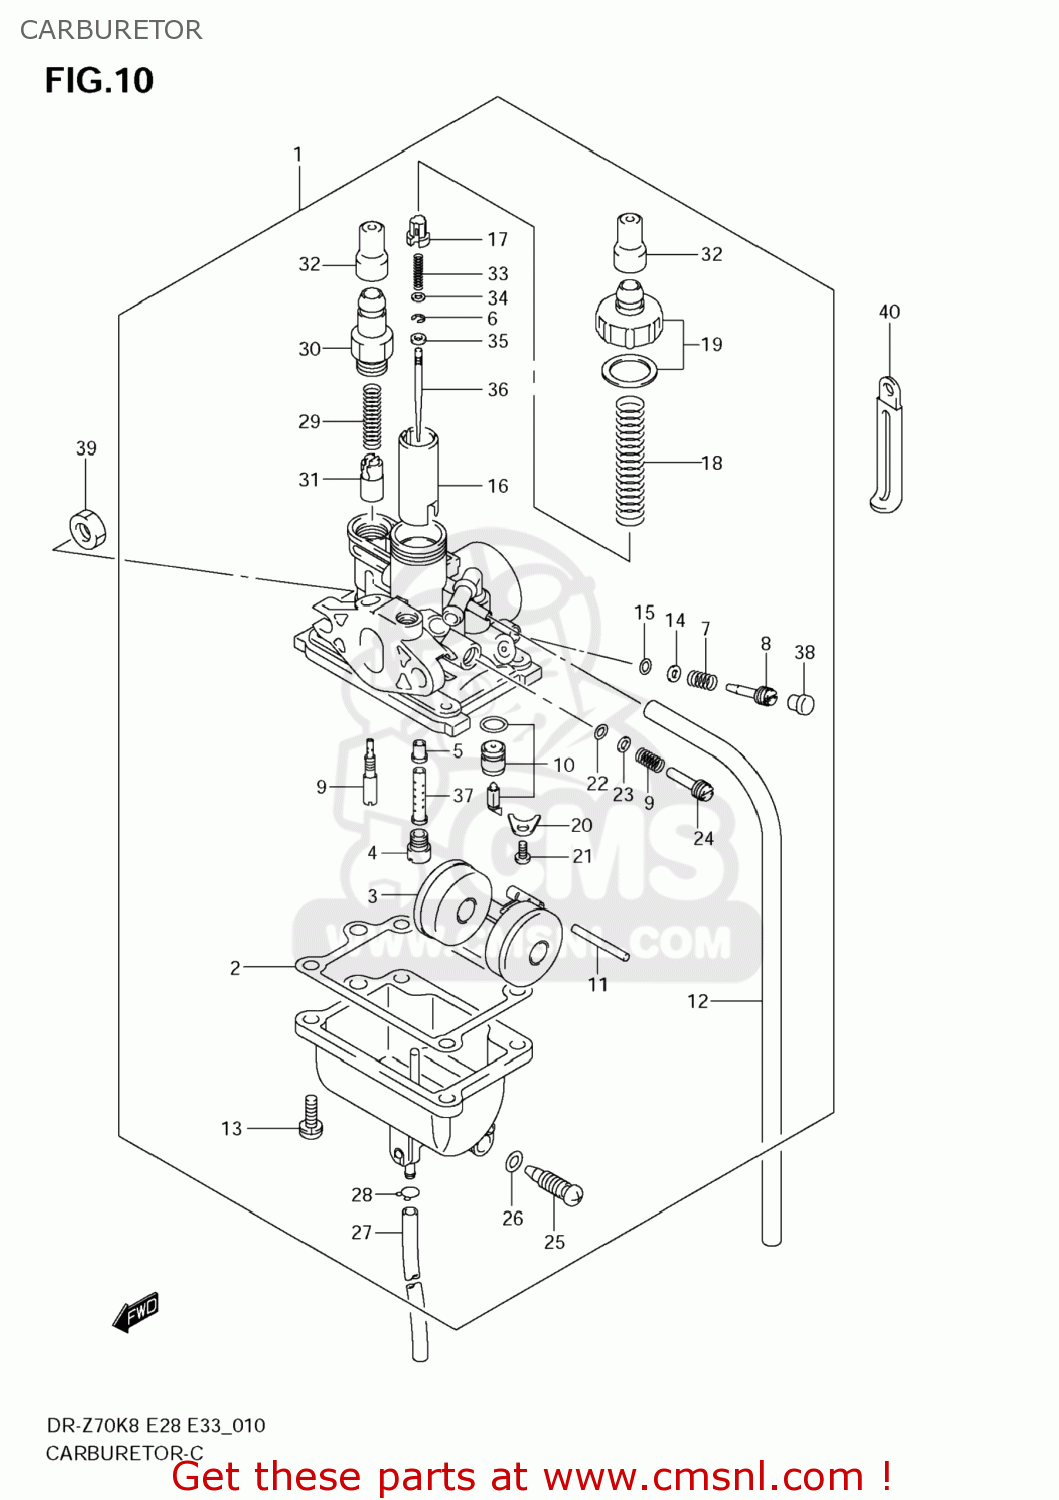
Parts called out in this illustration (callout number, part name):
1	CARBURETOR ASSY
2	GASKET (NAS)
3	FLOAT
4	JET,MAIN(55)
5	JET,NEEDLE
6	E RING
7	SPRING
8	SCREW,THROTTLE STOP
9	JET,PILOT(17.5)
10	VALVE ASSY,NEEDLE
11	PIN,FLOAT
12	HOSE(5X9X600)
13	SCREW
14	WASHER
15	O RING
16	VALVE,PISTON
17	HOLDER
18	SPRING
19	CAP
20	PLATE,NEEDLE VALVE FITING
21	SCREW
22	O RING,PILOT AIR SCREW
23	WASHER
24	ADJUSTER
25	SCREW,DRAIN
26	O RING
27	HOSE(3X7X600)
28	CLIP
29	SPRING
30	HOLDER,GUIDE
31	PLUNGER,STARTER
32	CAP
33	SPRING
34	WASHER
35	RING
36	NEEDLE,JET
37	PIPE
38	PLUG
39	NUT
40	CLAMP(L:80)
